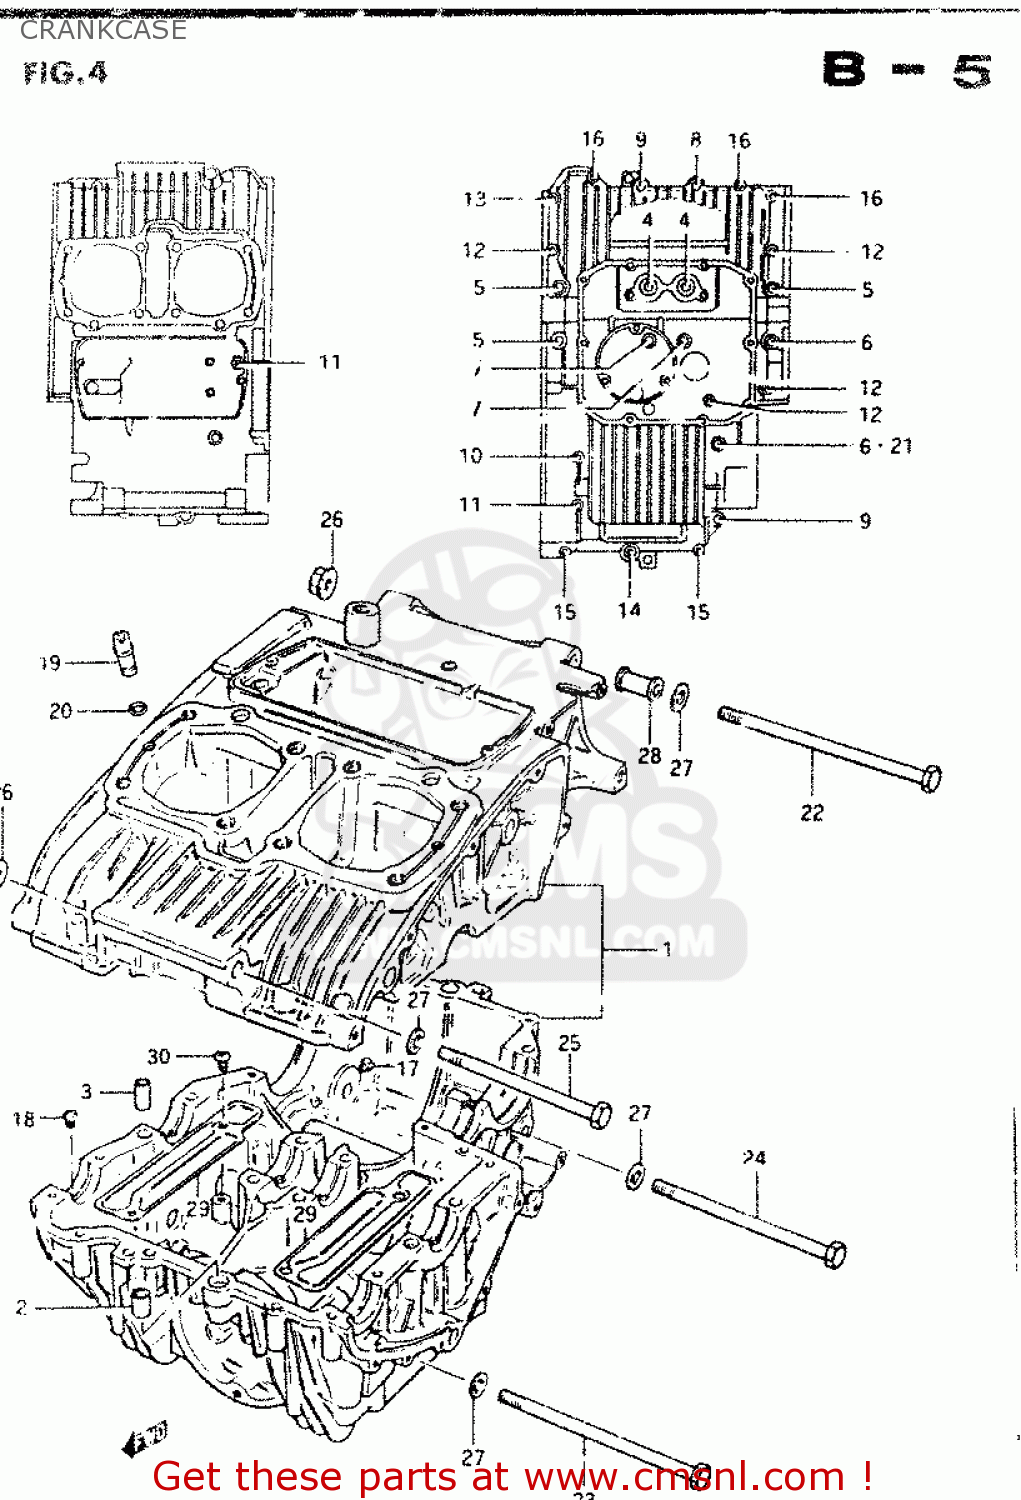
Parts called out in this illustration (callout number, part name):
1	CRANKCASE SET
2	PIN(10.4X13X22)
3	PIN (11X20)(SUS)
4	BOLT (8X70)
5	BOLT
6	BOLT
7	BOLT(8X100)
8	BOLT (8X65)
9	BOLT
10	BOLT(6X125)
11	BOLT(6X105)
12	BOLT (6X90)
13	BOLT
14	BOLT
15	BOLT 6X50
16	BOLT (6X45)
17	JET,AIR
18	JET
19	JET
20	O RING(D:1.05,ID:3.1)
21	GASKET 8.2X14X1 (NAS)
22	BOLT
23	BOLT
24	BOLT
25	BOLT
26	NUT 10MM
27	WASHER
28	SPACER,ENGINE MOUNT
29	PLATE,OIL SEPARATOR
30	SCREW
